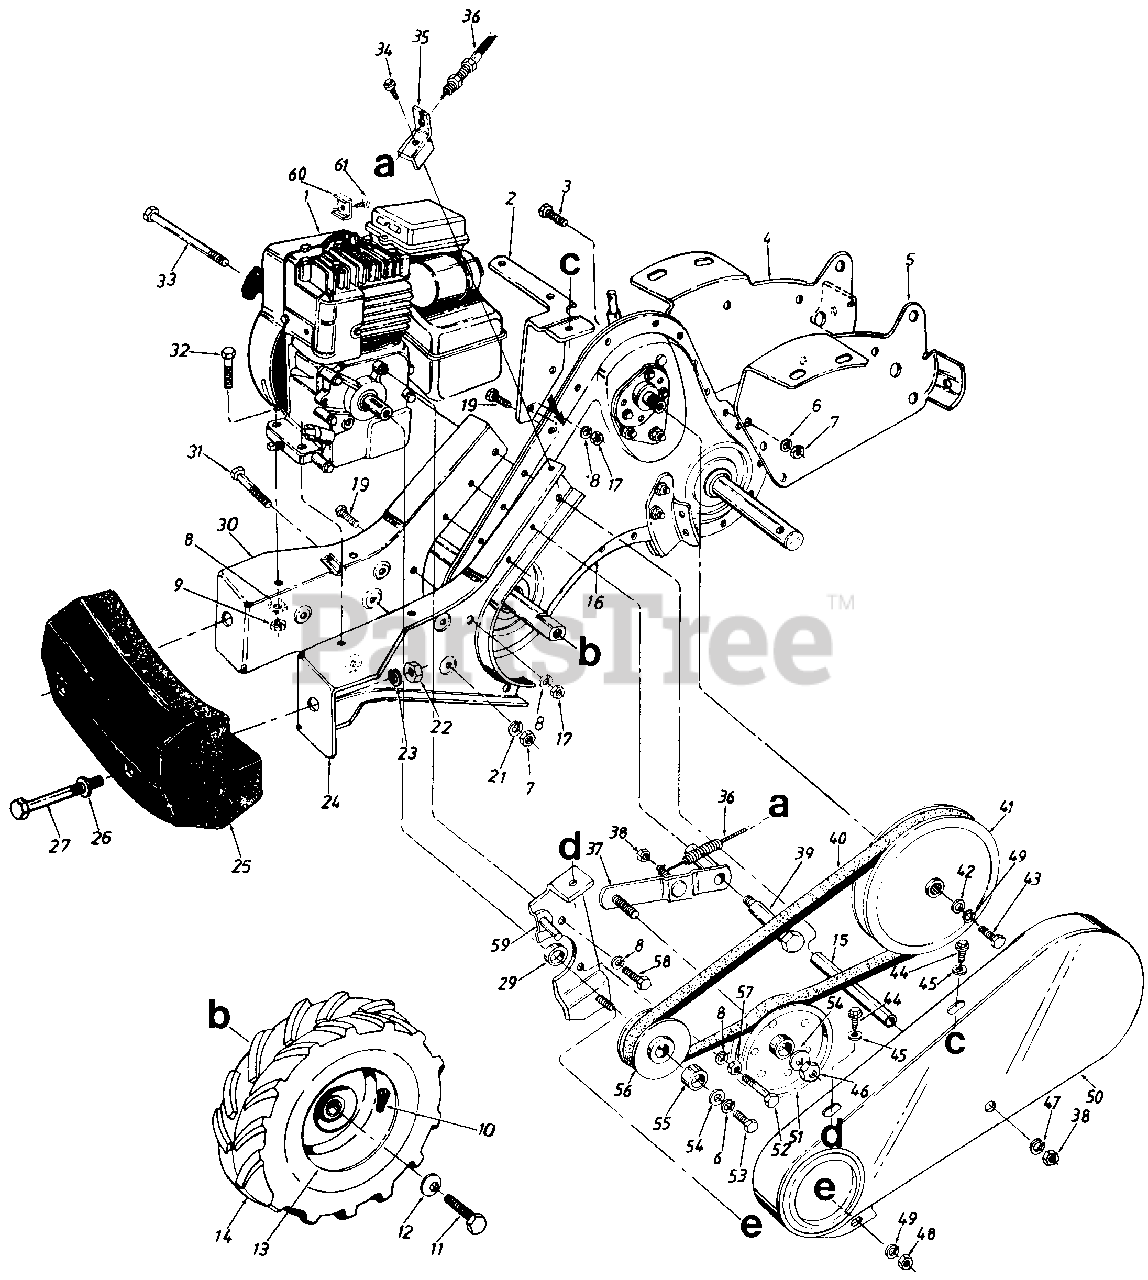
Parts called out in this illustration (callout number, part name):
1	Engine
2	Belt Cover Mounting Brkt.
3	Hex Bolt 3/8-16 x 1.00" Lg.*
4	Tine Shield Mtg. Brkt.-R.H.
5	Tine Shield Mtg. Brkt.-L.H.
6	L-Wash. 3/8" I.D.*
7	Hex Nut 3/8-16 Thd.
8	L-Wash. 5/16" I.D.*
9	Hex Nut 5/16-18" Thd.*
10	Air Valve
11	Hex Bolt 5/16-24 x .62" Lg.*
12	Bell-Wash. .345" I.D. x .88"
13	Wheel Rim Ass'y. Only
14	L.H. Wheel Ass'y. Comp.
14	R.H. Wheel Ass'y. Comp.
14	Tire Only 13 x 5.0
15	Spacer 3/8" I.D. x 3.38" Lg.
16	Transmission Comp.
17	Hex Nut 5/16-18 Thd.*
19	Hex Bolt 5/16-18 x .75" Lg.
21	L-Wash. 3/8" I.D.-H.D.
22	Hex Nut 1/2-13 Thd.*
23	L-Wash. 1/2" I.D.
26	Fl-Wash. .510" I.D. x 1.0"
27	Hex Bolt 1/2-13 x 5.00" Lg.*
29	Spacer .79" I.D. x 1" O.D. (420 Only)
32	Hex Bolt 5/16-18 x 1.50"*
33	Hex Bolt 5/16-18 x 4.75 Lg.-Gr. 2
34	Hex Wash. TT-Tap Scr. 5/16-18 x .62" Lg.
35	Bracket Clutch Cable
36	Clutch Control Cable 53" Lg.
39	Shld. Bolt .500" Dia. x 2.27"
40	V-Belt
41	V-Pulley Split 5/8" I.D.
42	Fl-Wash. 1/4" I.D. x .93" O.D.
43	Hex Bolt 1/4-28 x .75" Lg.
44	Hex Wash. Hd. S-Tap Scr. 1/4-20 x .50" Lg.
45	Fl-Wash. .281" I.D. x .625"
46	Hex Cent. L-Nut 3/8-24 Thd.
47	Fl-Wash. 5/16" I.D.
48	Hex Nut 1/4-20 Thd.*
49	L-Wash. 1/4" I.D.
51	Fl-Idler w/Flanges 3.75" O.D.
52	Hex Bolt 5/16-24 x 1.75
53	Hex Bolt 3/8-24 x 1.00" Lg.
54	Fl-Wash. 3/8" I.D. x 1.00"
55	Spacer .758" I.D. x .990"
56	Engine Pulley
57	Hex Nut 5/16-24 Thd.
58	Hex Bolt 5/16-24 x .62" Lg.
61	Hex Sems Scr. #10-32 x .62
